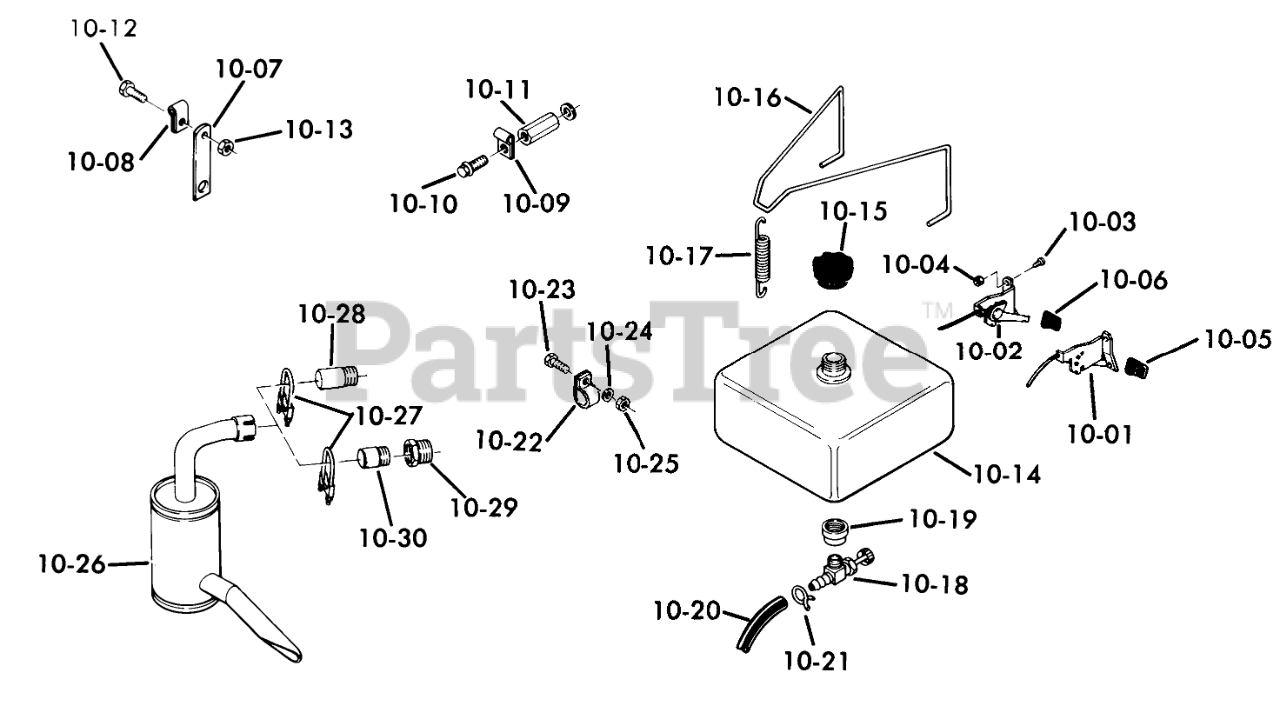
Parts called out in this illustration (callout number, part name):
10-01	Choke Control
10-02	THROTTLE CONTROL
10-03	SCREW
10-04	#10-24 Kep-Nut
10-05	KNOB-CHOKE
10-06	KNOB-THROTTLE
10-07	Strap
10-08	THROTTLE CONTROL CLP
10-09	Clip
10-10	Screw
10-11	Special Nut
10-12	Screw
10-13	Nut
10-14	ASSY-FUEL TANK
10-15	Cap
10-16	HOLD DOWN WIRE
10-17	CLUTCH SPRING
10-18	VALVE-FUEL
10-19	BUSHING
10-20	Fuel Hose
10-21	Clamp
10-22	CLAMP-HOSE
10-23	Bolt
10-24	WASHER 5/16 SAE
10-25	Nut
10-26	Muffler
10-27	ASSY-MUFFLER CLAMP
10-28	NIPPLE
10-29	REDUCER 1 1/4-1
10-30	NIPPLE- 1X2 SPECIAL
